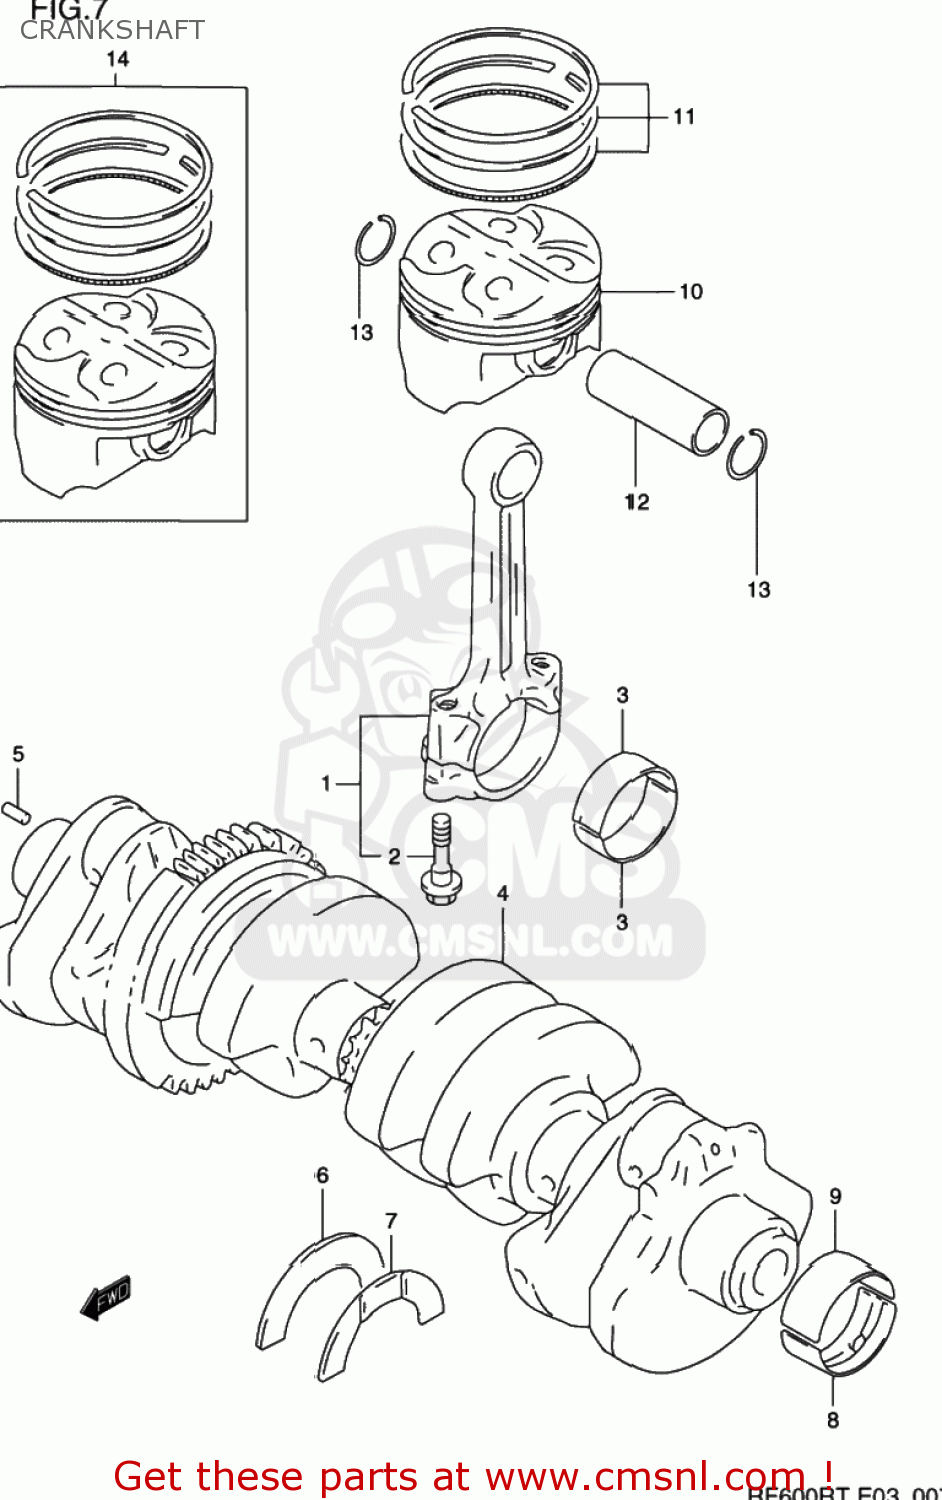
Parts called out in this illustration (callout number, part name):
1	CONNECTING ROD ASSY
2	BOLT,CONNECTING ROD
3	BEARING,CRANK PIN
4	CRANKSHAFT SET
5	PIN
6	BEARING,CRANK THRUST(GREEN)
7	BEARING,CRANK THRUST(RED)
8	BEARING,CRANKSHAFT(GREEN)
9	BEARING,CRANKSHAFT(GREEN)
10	PISTON
11	RING SET,PISTON
12	PIN,PISTON
13	RING,SNAP 16MM
14	PISTON SET (OS:0.5)
